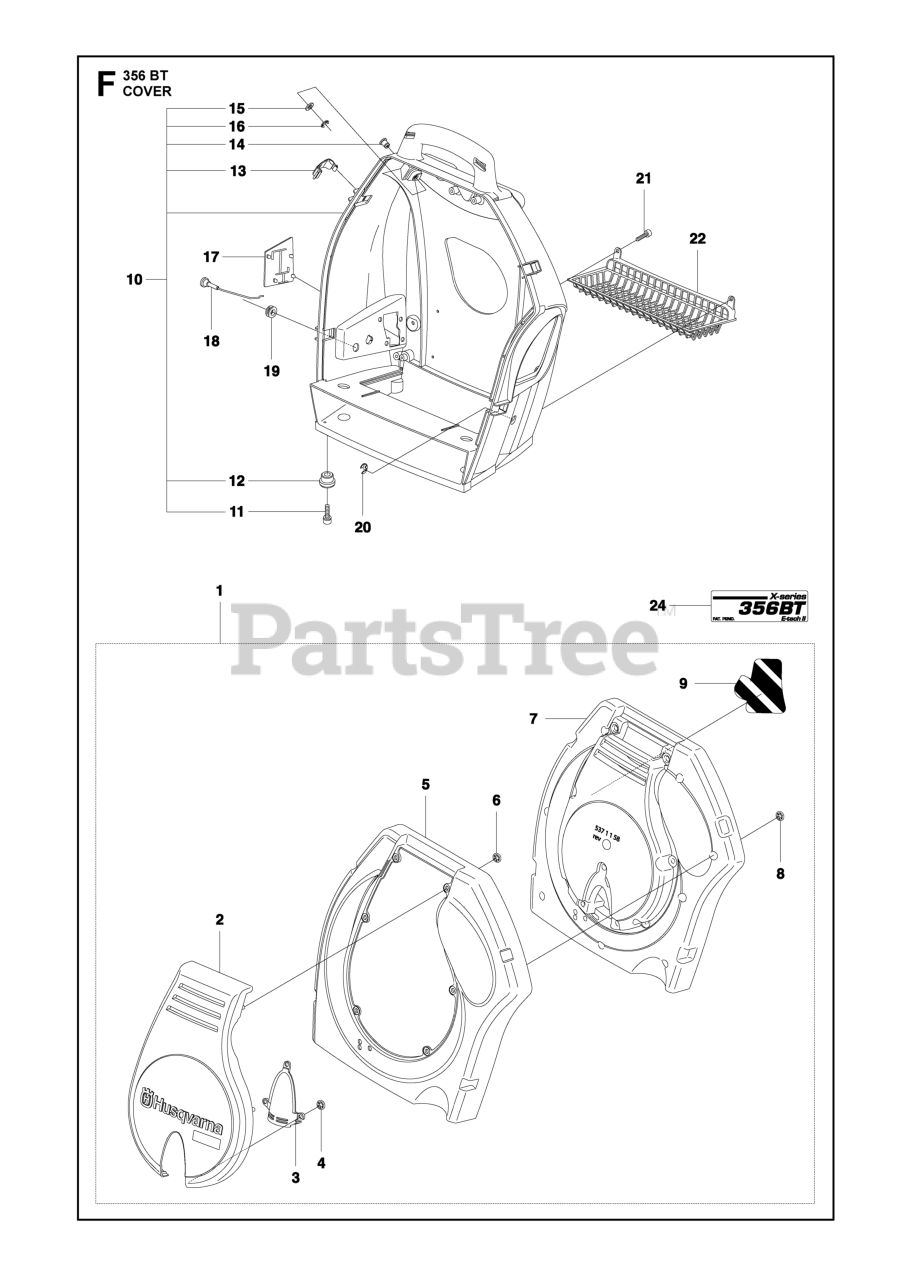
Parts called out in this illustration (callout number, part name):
4	Locking Washer
6	Locking Washer
7	INSULATION **
8	Locking Washer
13	BUCKLE ORANGE
14	SLEEVE, CHASSIS
16	RETAINING RING
17	COVER
18	CHOKE CONTROL
20	E-RING
24	DECAL
